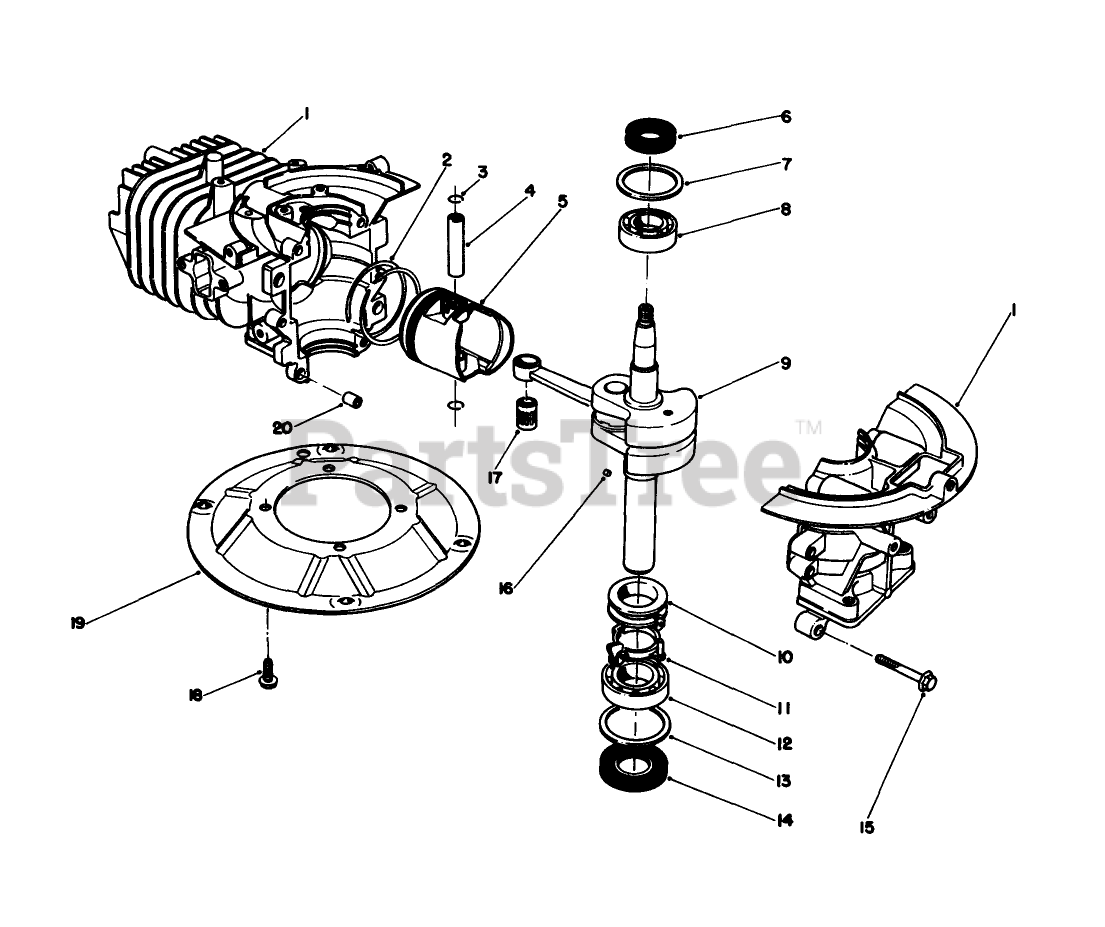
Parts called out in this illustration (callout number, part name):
1	SCREW
3	FLYWHEEL
5	COIL-MAGNETO
6	CLAMP
7	Sparkplug
8	PROTECTOR-PLUG
9	SCREW
10	CAP-SPARKPLUG
